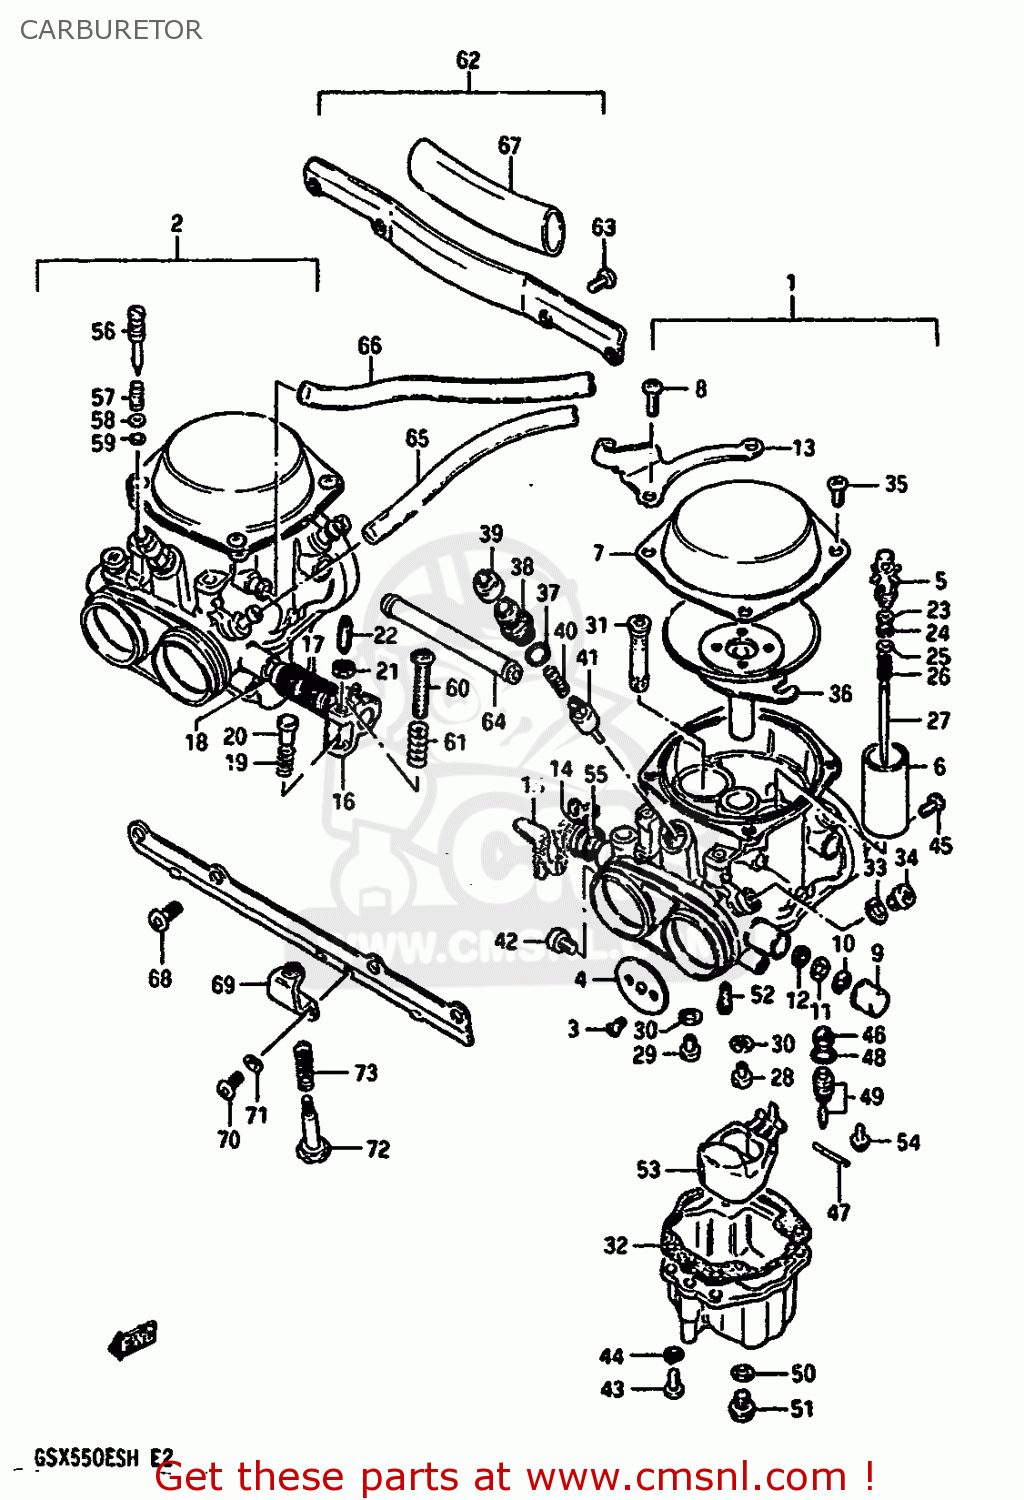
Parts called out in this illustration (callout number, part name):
1	CARBURETOR,LH
2	CARBURETOR,RH
3	SCREW
4	VALVE,THROTTLE
5	HOLDER,GUIDE
6	VALVE,THROTTLE
7	COVER,DIAPHRAGM
8	SCREW
9	CAP,THROTTLE SHAFT
10	E RING
11	GASKET,THROTTLE SHAFT (NAS)
12	SEAL
13	BRACKET,THROTTLE CABLE
14	SPRING,THROTTLE SHAFT
15	SHAFT ASSEMBLY
16	SHAFT ASSEMBLY
17	SPRING
18	RING
19	SPRING,THROTTLE SCREW
20	PIN,THROTTLE LEVER
21	NUT
22	SCREW
23	RING
24	CAP,LEVER
25	WASHER
26	SPRING
27	NEEDLE, JET (5C13-3)
28	JET,MAIN(90)
29	JET,MAIN
30	WASHER,NEEDLE NOZZLE
31	JET,NEEDLE
32	GASKET,FLOAT CHAMBER (MCA)
33	WASHER
34	SCREW
35	SCREW
36	DIAPHRAGM,CARBURETOR
37	O RING
38	HOLDER,GUIDE
39	CAP
40	SPRING
41	VALVE,STARTER
42	SCREW
43	SCREW
44	LOCK WASHER
45	JET
46	FILTER
47	PIN,FLOAT
48	O-RING,NEEDLE VALVE
49	VALVE ASSEMBLY,NEEDLE
50	GASKET (NAS)
51	PLUG,DRAIN
52	JET(40)
53	FLOAT
54	SCREW
55	RING,THROTTLE SHAFT
56	SCREW,PILOT AIR
57	SPRING
58	GASKET
59	O-RING
60	SCREW
61	SPRING
62	FLANGE ASSEMBLY,CARBURETOR
63	SCREW
64	PIPE,CARBURETOR
65	HOSE 4.5X8X600
66	HOSE
67	HOSE(16X19X100)
68	SCREW
69	BRACKET,SLOW ADJUST
70	SCREW
71	LOCK WASHER
72	ADJUSTER
73	SPRING
